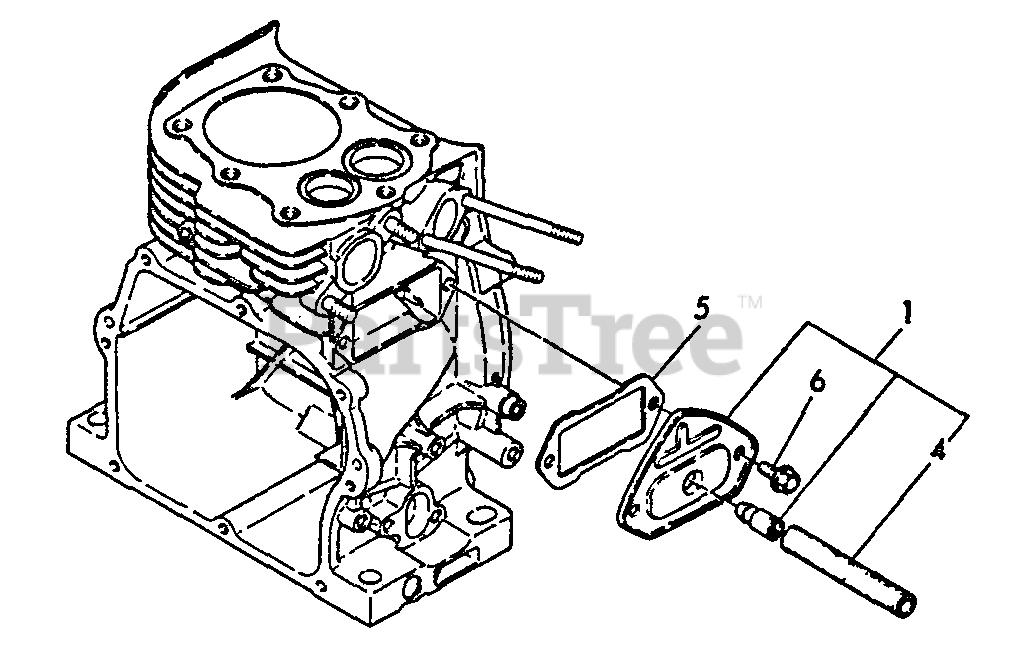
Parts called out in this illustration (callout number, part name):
1	VENT, FUEL TANK
4	PIPE - BREATHER
5	GASKET, BREATHER
6	BOLT - 6X8 -- PLATED
